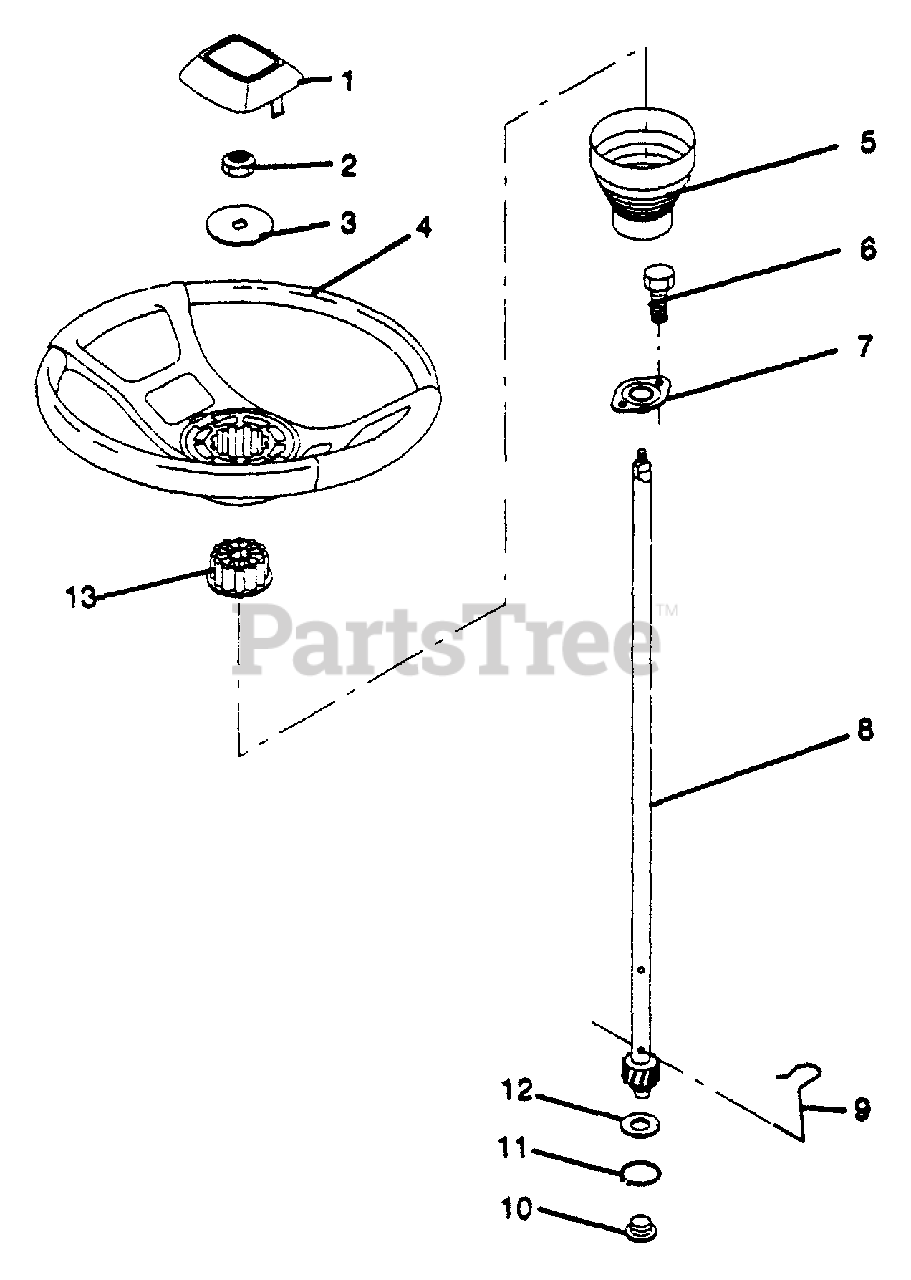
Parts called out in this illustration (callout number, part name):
1	Insert, Wheel, Steering
2	Locknut 3/8-24 UNF
3	Washer 13/32 x 2-3/8 x 8 Ga.
4	Wheel, Steering
5	Sleeve, Steering
6	Screw, Hex SLFTP #10-16 x 1/2 TY-B
7	Bushing, Steering
8	Shaft, Steering
9	Clip Steering
10	Bushing, Lower, Steering
11	Ring, Retaining
12	Washer 21/32 x 1 x 16 Ga.
13	Adapter, Wheel, Steering
